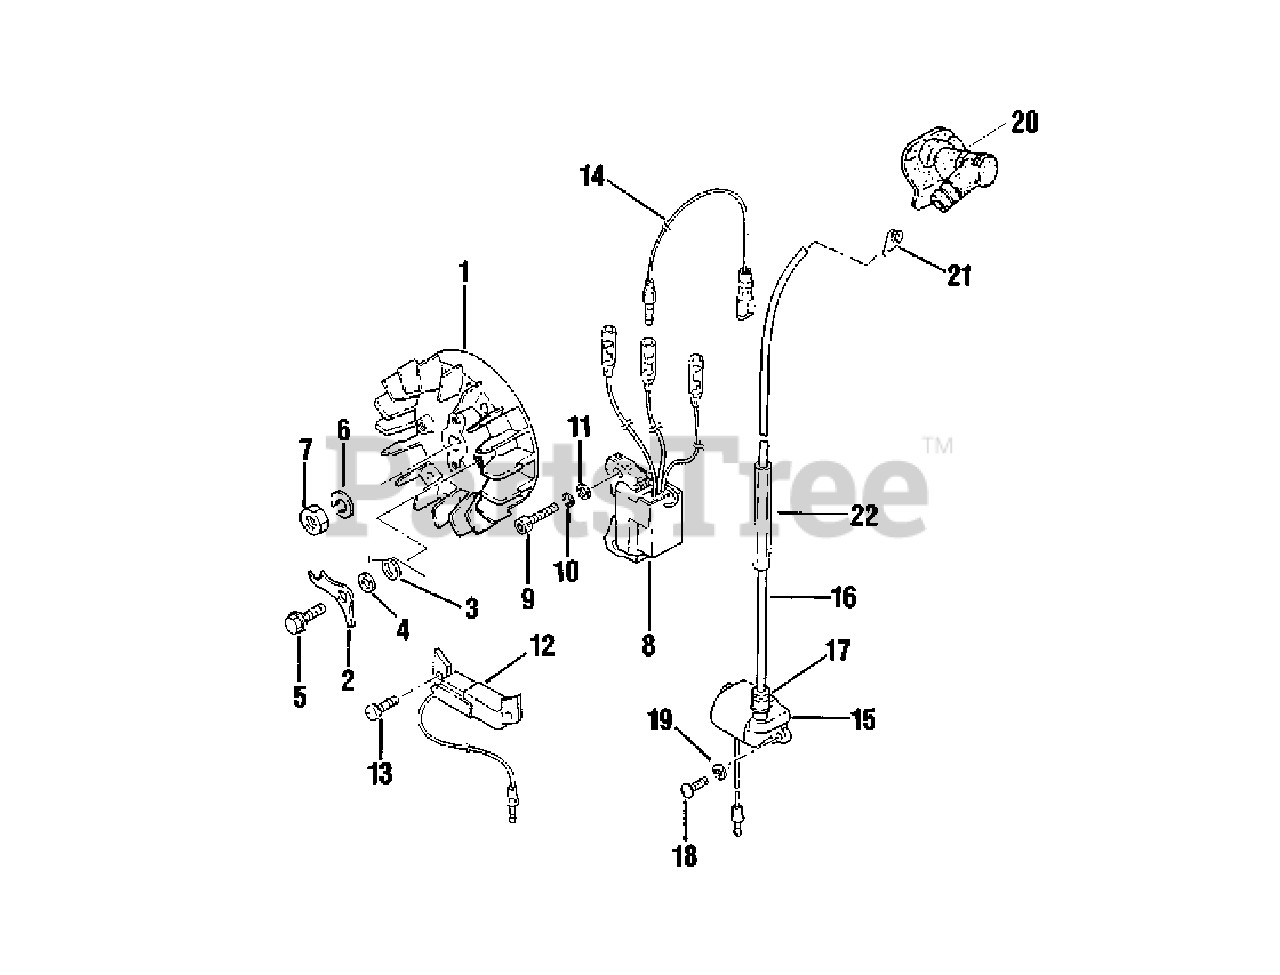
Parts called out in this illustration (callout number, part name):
1	ROTOR ASSY
2	RATCHET
3	SPRING, RATCHET
4	WASHER 6 MM
5	BOLT
6	WASHER, SPRING 8
7	NUT
8	EXCITER, COIL
9	BOLT 5×20
10	WASHER, SPRING 5
11	WASHER, FLAT 5.5×10×0.8
12	PULSER COIL
15	IGNITION COIL ASSY
17	CAP
19	WASHER 4.3×9.6×0.8
20	CAP, SPARK PLUG
21	TERMINAL, SPARK PLUG
22	PROTECTOR
